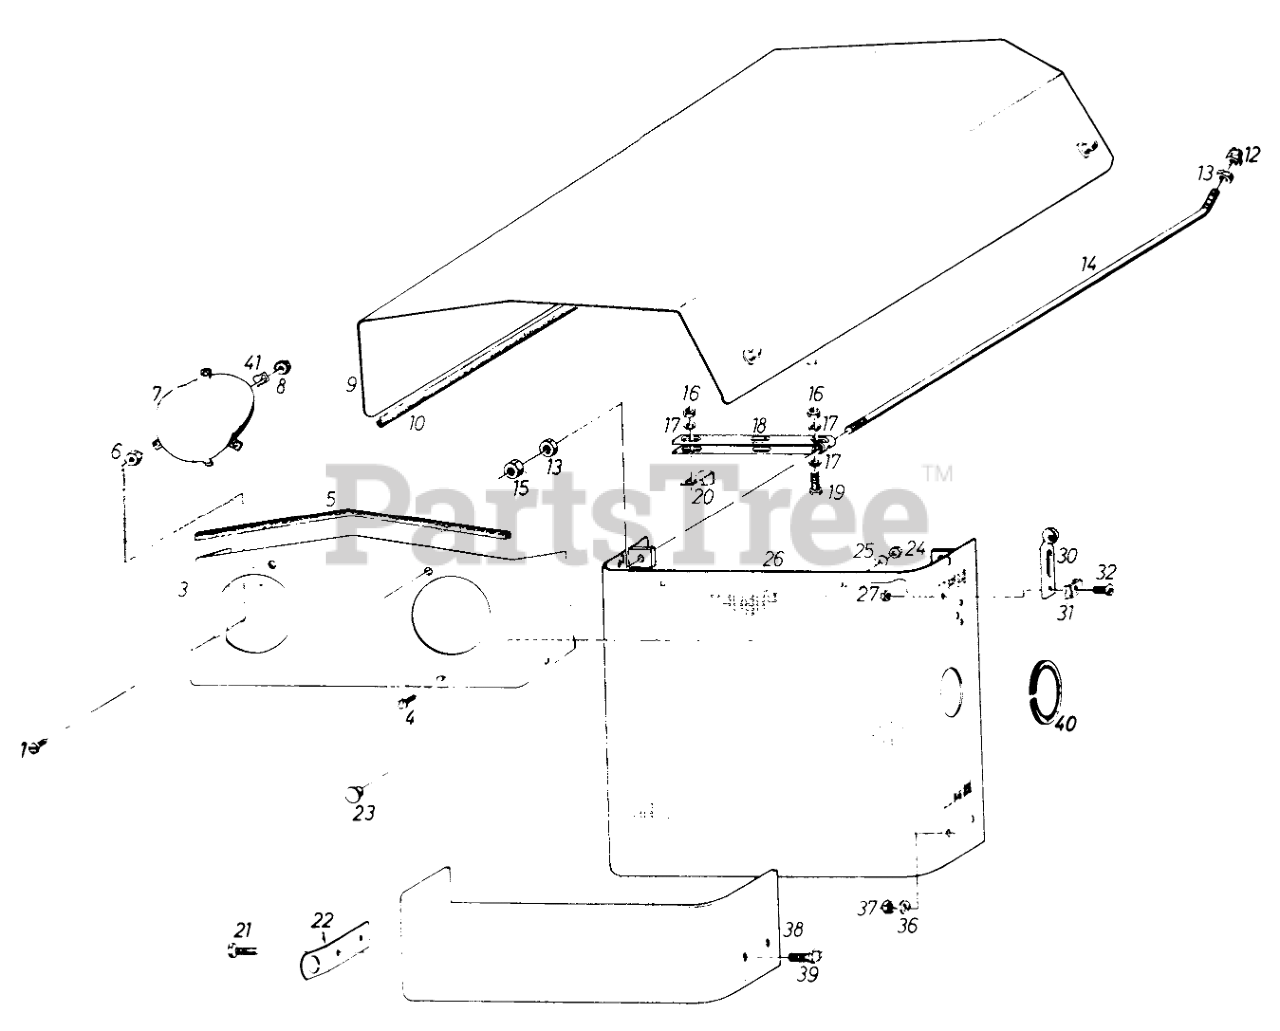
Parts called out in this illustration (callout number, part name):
1	Screw
3	Front Bonnet Assy
4	Screw
5	Cushion
7	Head-Light
9	Hood Assy
10	Cushion
17	Washer
18	Bracket
20	Support
22	Bracket
25	Washer
26	Grill
30	FASTENING STRAP
31	CLAMP
32	Screw
36	Washer
38	Bumper
40	Cushion
41	Clamp
